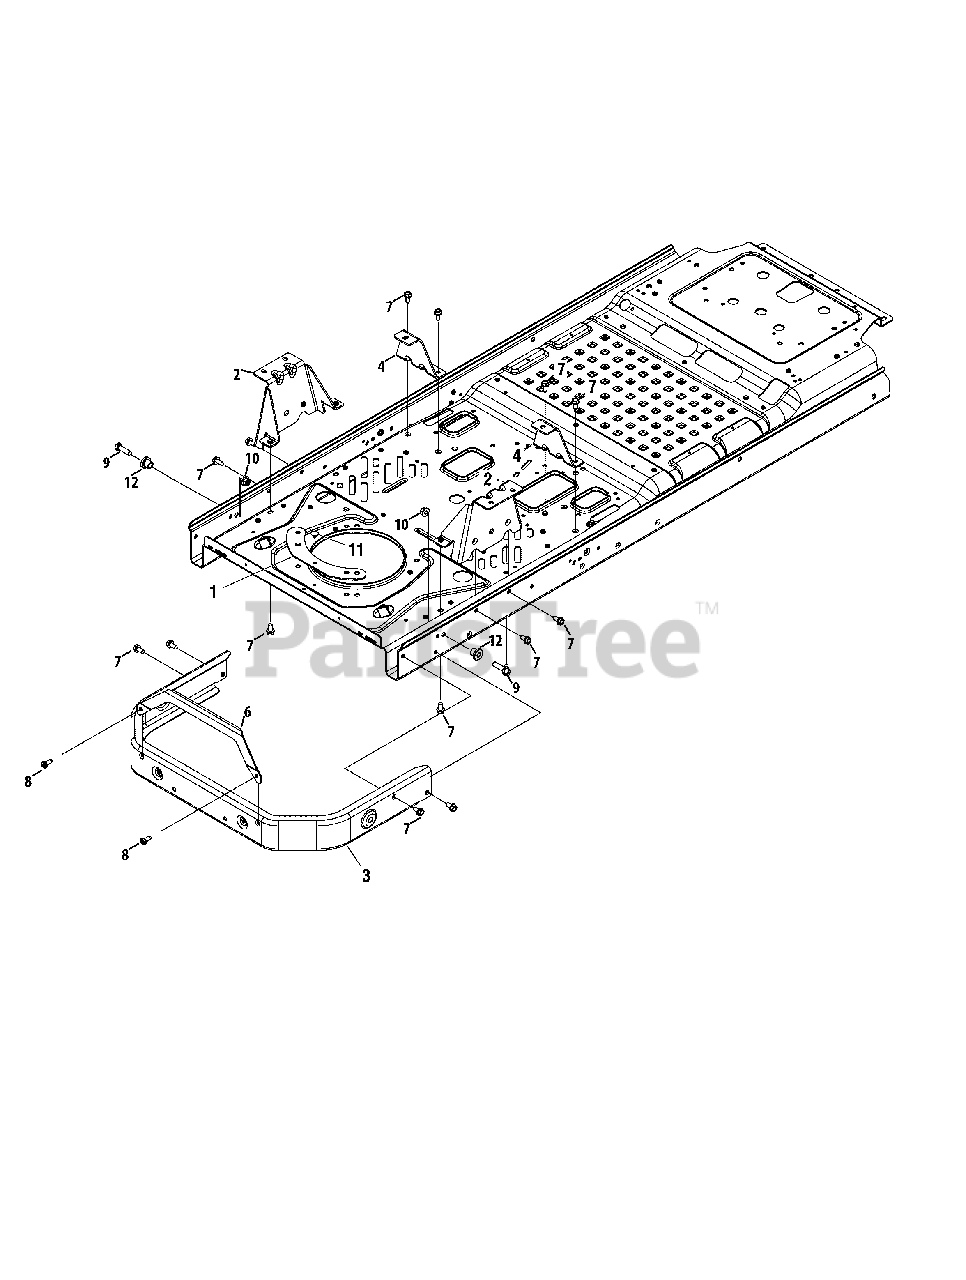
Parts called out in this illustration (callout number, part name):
1	PLATE, Retainer
2	BRACKET, Transmission Mounting (RH)
3	BUMPER, Bumper
4	BRACKET, Transmission Mounting (LH)
6	BRACKET, Rear Muffler Shield
7	SCREW, 5/16-18 X .750, Hex Washer
8	SCREW, 5/16-18, 0.750, Self-Tapping
9	SCREW, 3/8-16 X 1.25, Hex
10	NUT, 3/8-16, Flanged Lock, GR5, Zinc/Clear
11	CLIP, .250 DIA. X .500 LG
12	SPACER, .38 X 1.0 X .70, Shoulder
